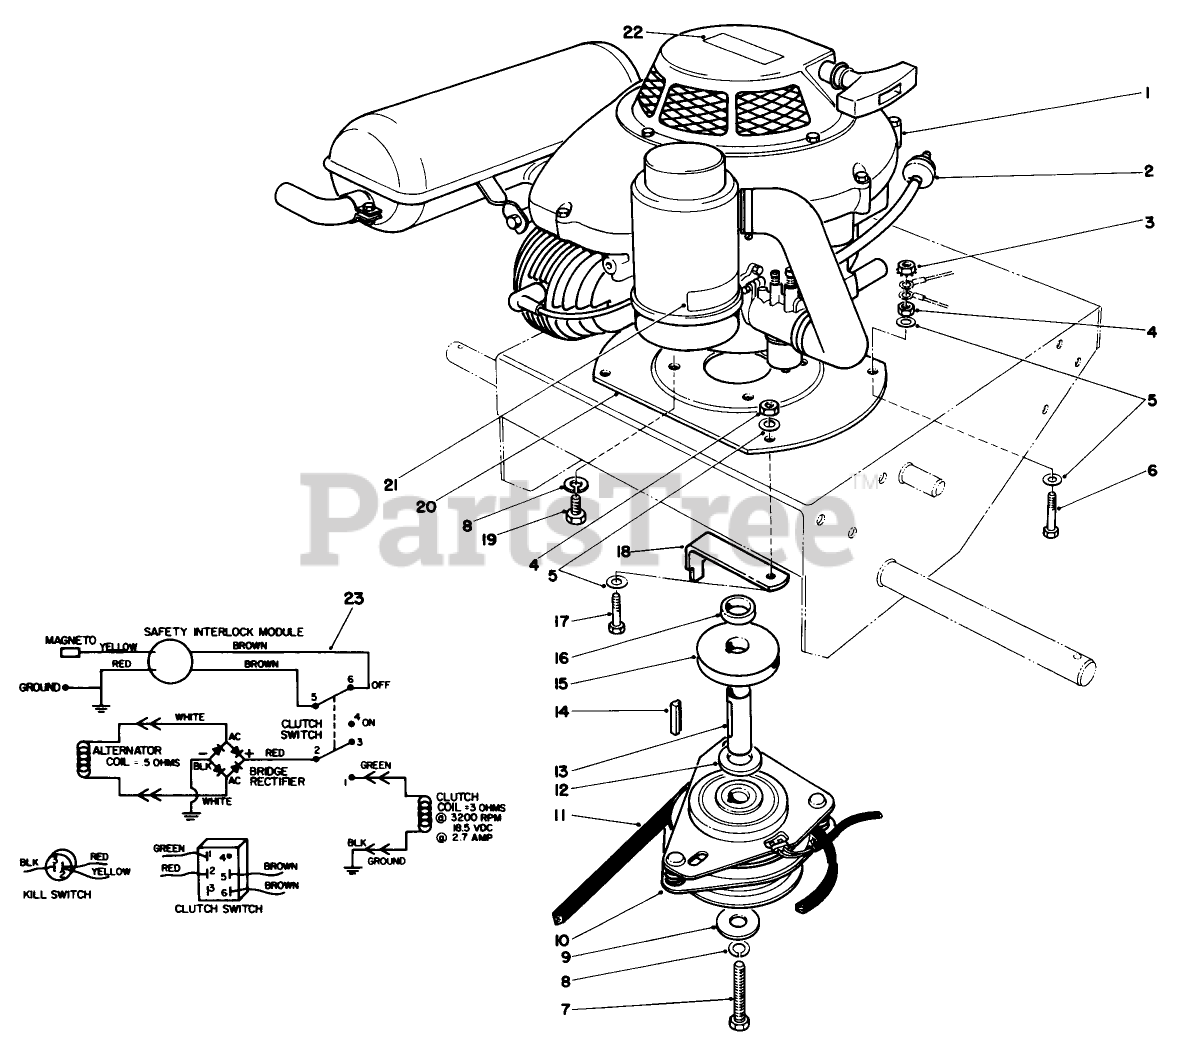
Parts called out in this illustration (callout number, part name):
2	SCREW-HH
3	NUT-LOCK, CONE
4	ANCHOR-SPRING, DECK
5	SPRING-EXTENSION, DECK
6	SCREW-HH
7	PULLEY-IDLER
8	SCREW-HH
9	NUT-HEX
10	SPRING
11	V-BELT-DECK
12	BRACKET-PIVOT
13	DEFLECTOR ASM
13:2	DECAL-DANGER
13:3	DECAL-DANGER
14	PIN-HAIR
15	PIN-CLEVIS
17	Deck ASM
17	SPINDLE HOUSING ASM
17:1	BEARING-BALL
17:2	FITTING-GREASE
17:3	NUT-HEX
17:4	WASHER-LOCK
17:6	SCREW-BLADE
17:8	CUP-SCALP, ANTI
17:9	SPACER-SPINDLE
17:10	SPACER-BEARING
17:11	HOUSING-SPINDLE
17:13	WASHER
21	SCREW-HH
28	BRACKET-COVER, RH ASM
29	SCREW-CARR
30	NUT-LOCK, NI
31	LEVER-DECK ASM
32	SCREW-SHOULDER
33	WASHER
34	BRACKET-COVER, LH ASM
35	SCREW-CARR
36	ROLLER
37	PIN-COTTER
38	SHAFT-ROLLER
39	ROLLER-DECK
40	ROD-ROLLER
41	PIN-SPECIAL
44	WASHER-FLAT
45	BUSHING-PULLEY
46	DECAL-TORQUE, BLADE BOLT
47	DECAL-DANGER
